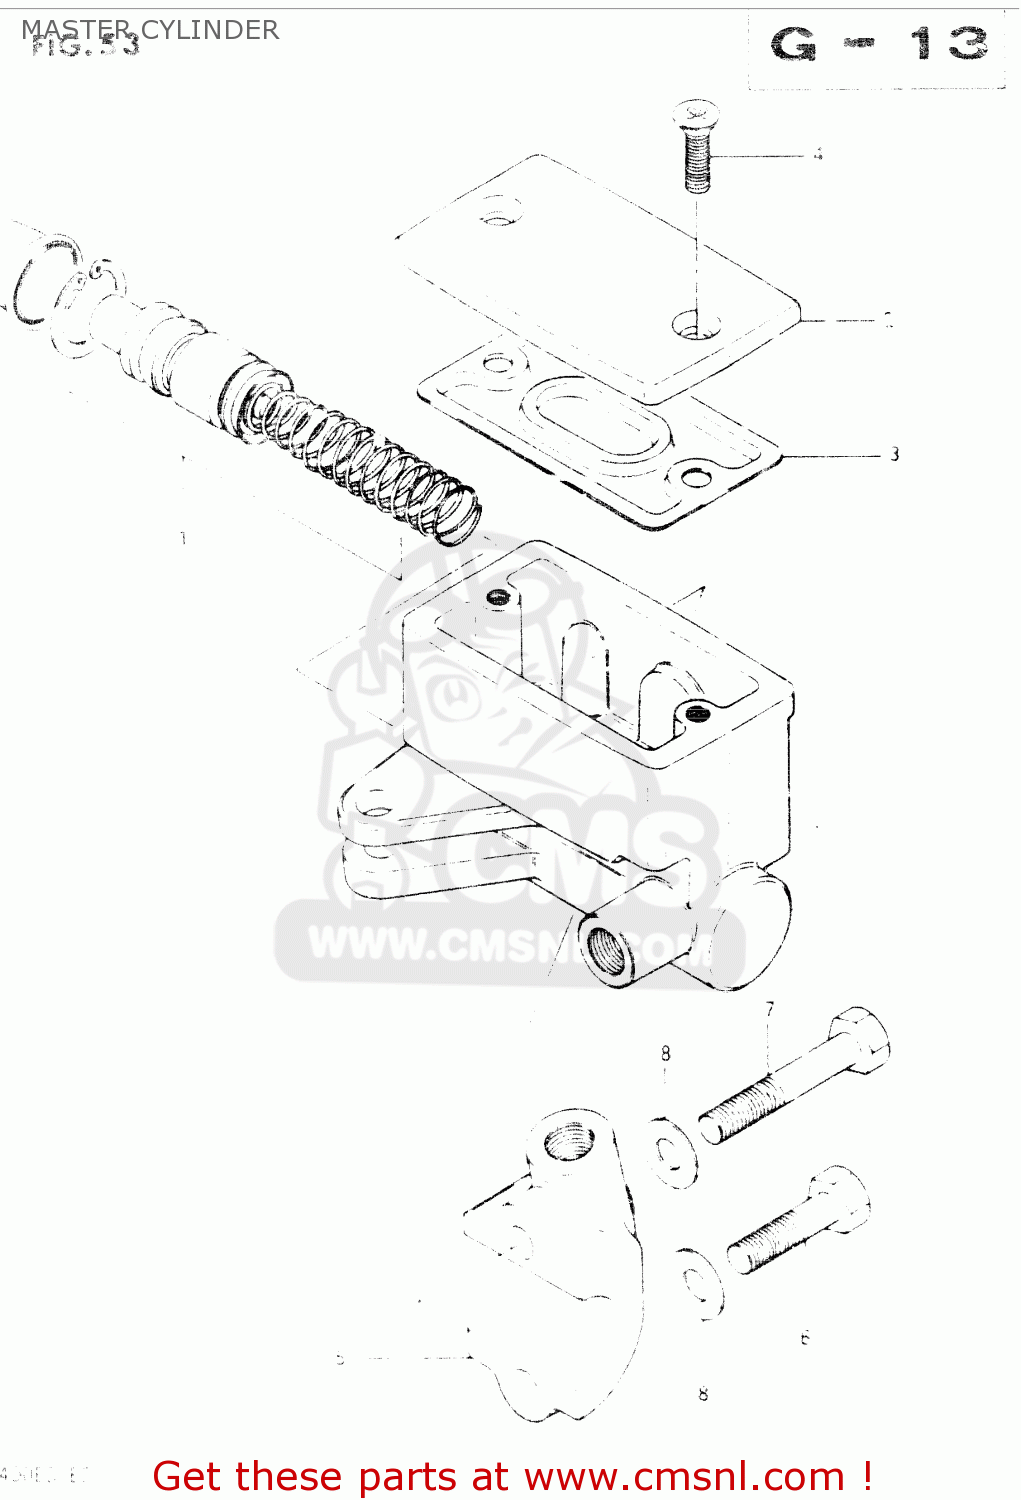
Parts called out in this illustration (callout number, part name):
1	PISTON & CUP SET
2	CAP
3	4
4	SCREW
5	HOLDER
6	BOLT
7	BOLT
8	WASHER
